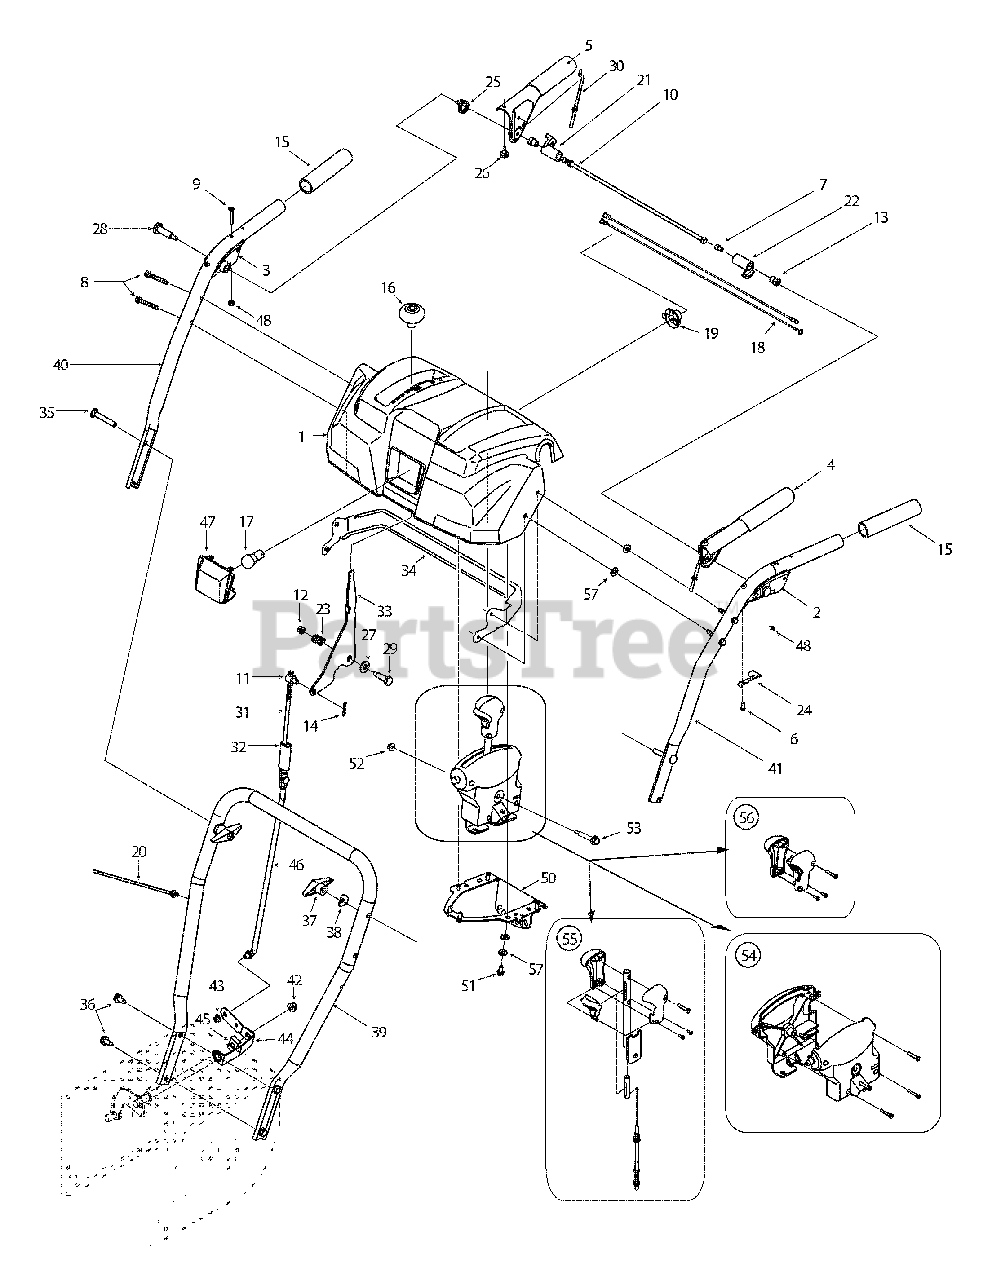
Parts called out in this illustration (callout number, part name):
1	Panel Assembly, Handle, Q-Style
2	Handle Assembly, Clutch Lock, LH
3	Handle Assembly, Clutch Lock, RH
4	Handle Assembly, Engagement, LH
5	Handle Assembly, Engagement, RH
6	Screw, #8-16 x .50
7	Screw, 1/4-20 x .375
8	Screw, Self-tapping, 1/4-20 x 1.750
9	Screw, Machine, #10-24 x 1.375
10	Rod, Pivot
11	Ferrule, 5/16-18 x .312
12	Nut, Flange Lock, Nylon, 1/4-20
13	Nut, Shoulder, Hex, 1/4-20,
14	Pin, Cotter, .072 Dia. x 1.13
15	Grip, 1.0 ID x 5.0
16	Knob, Shift
17	Lamp
18	Harness, Headlight
19	Socket, Lamp
20	Tie, Cable, 19 x 8.39", Tree Mount
21	Plate, Lock
22	Cam, Clutch Lock
23	Spring, Compression, .39 x .60 x .88
24	Spring, Clutch, Lock
25	Spring, Torsion, 0.8156 ID x .3038
26	Bumper, Rubber, .62 OD x .22
27	Washer, Flat, .385 x .870 x .092
28	Screw, Shoulder, .437 x 1.345, 1/4-20
29	Screw, Shoulder, .374 Dia. x 1.05
30	Z-Fitting, Cable
31	Rod, Shift, .312 x 8.98 Upper
32	Connector Sleeve, Shift Rod
36	Screw, 5/16-12, 0.750
37	Wing Knob, 5/16-18
38	Washer, Saddle, 320 x .93 x .060
39	Handle, Lower, Snow
40	Handle, Upper, RH
41	Handle, Upper, LH
42	Nut, Flange Lock, Nylon, 5/16-18
43	Nut, Speed, .3125 Dia.
44	Spring Lever, Shift
45	Bracket, Shift Spacer
46	Shift Rod, Lower
47	Lens
48	Nut, Hex Lock, Nylon, #10-24, Gr2
51	Screw, 1/4-15 x .50
52	Nut, Hex Lock, 1/4-20
53	Bolt, Shoulder, 5/16 x 1.7, 1/4-20
54	Kit, Chute Control Housing
55	Kit, Lever Tube w/Cable
56	Kit. 4-Way Knob
57	Washer, Flat, .25 x .630 x .051
